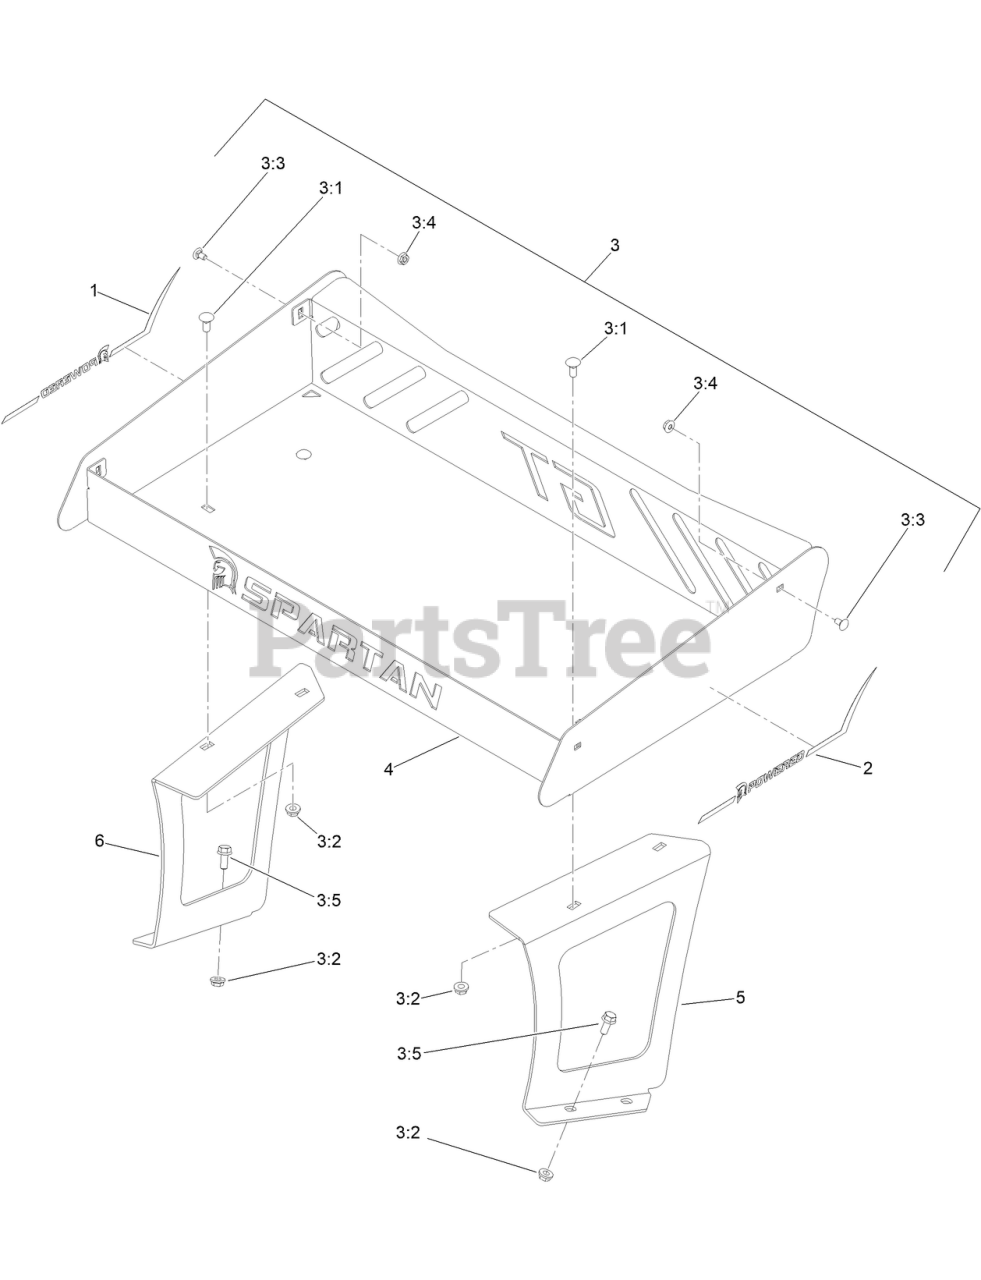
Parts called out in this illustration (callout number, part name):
1	DECAL-POWERED WING
2	DECAL-POWERED WING
3	SPOILER HARDWARE KIT
3:1	BOLT-CARR
3:3	SCREW-CARR
3:4	1/4-20 HEX FLANGE NUT
3:5	SCREW-HHF
4	SPARTAN REAR BASKET PAINTED
5	KGZ REAR BASKET LEFT MOUNT
6	KGZ REAR BASKET RIGHT MOUNT
